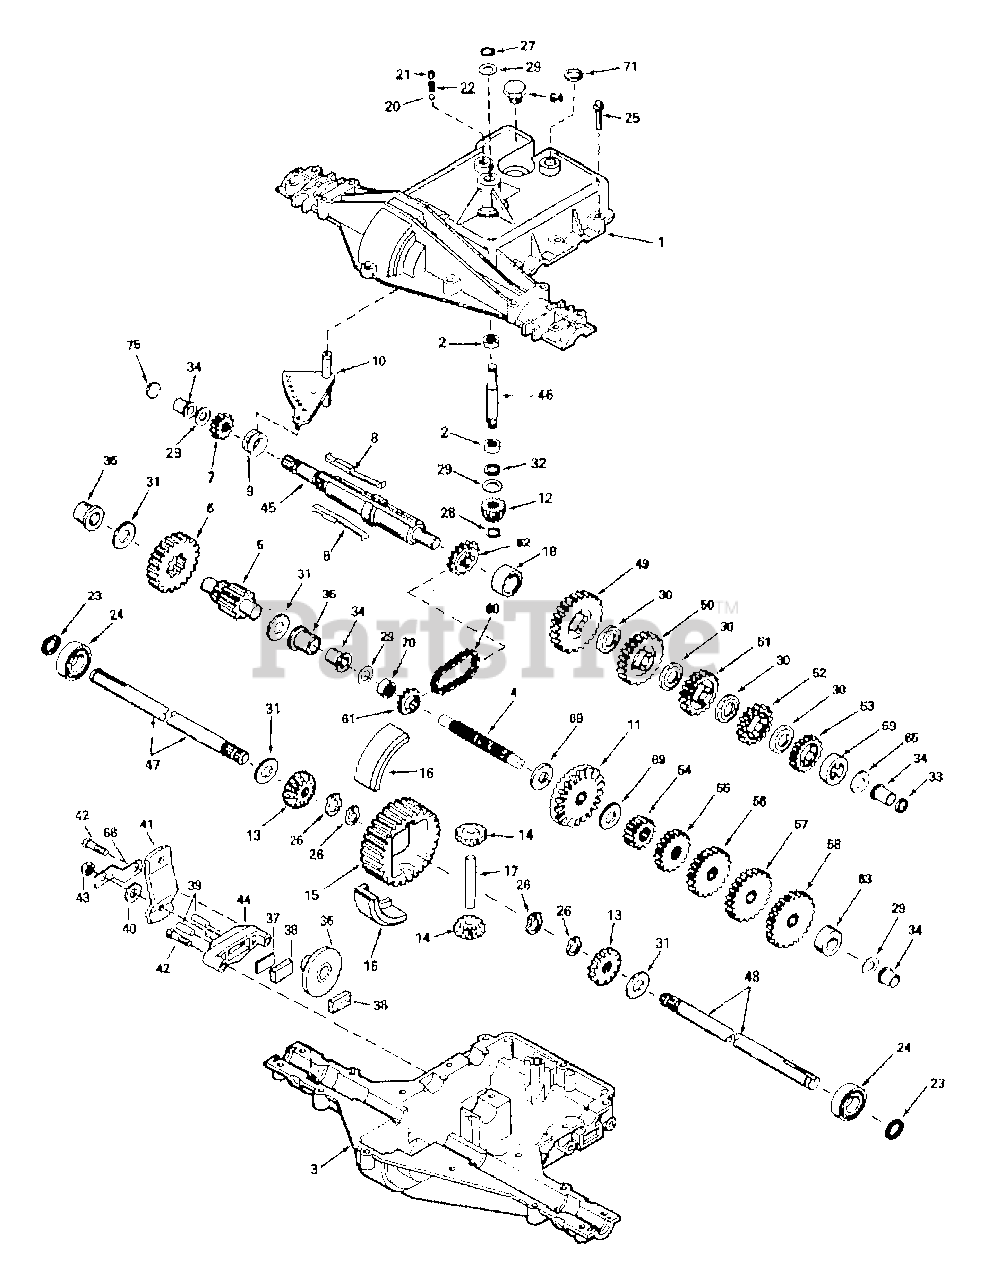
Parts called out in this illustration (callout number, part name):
2	NEEDLE BEARING
4	COUNTERSHAFT
5	SHAFT & GEAR
6	OUTPUT GEAR
7	SPUR GEAR
8	SHIFT KEY
10	ROD & FORK
11	BEVEL GEAR
12	INPUT PINION
13	BEVEL GEAR
14	BEVEL GEAR
15	RING GEAR
16	BEARING BLOCK
17	DRIVE PIN
22	SPRING
23	SEAL
24	BALL BEARING
26	RET RING
27	RET RING
28	RET RING
29	WASHER
30	WASHER
32	O RING
34	BUSHING
36	BRAKE DISK
37	BRAKE PAD PLATE
38	BRAKE PAD
39	DOWEL PIN
41	BRAKE LEVER
45	BRAKE SHAFT
46	INPUT SHAFT
49	SPUR GEAR
50	SPUR GEAR
51	SPUR GEAR
52	SPUR GEAR
53	SPUR GEAR
54	SPUR GEAR
55	SPUR GEAR
56	SPUR GEAR
57	SPUR GEAR
58	SPUR GEAR
60	ROLLER CHAIN
61	SPROCKET
62	SPROCKET
